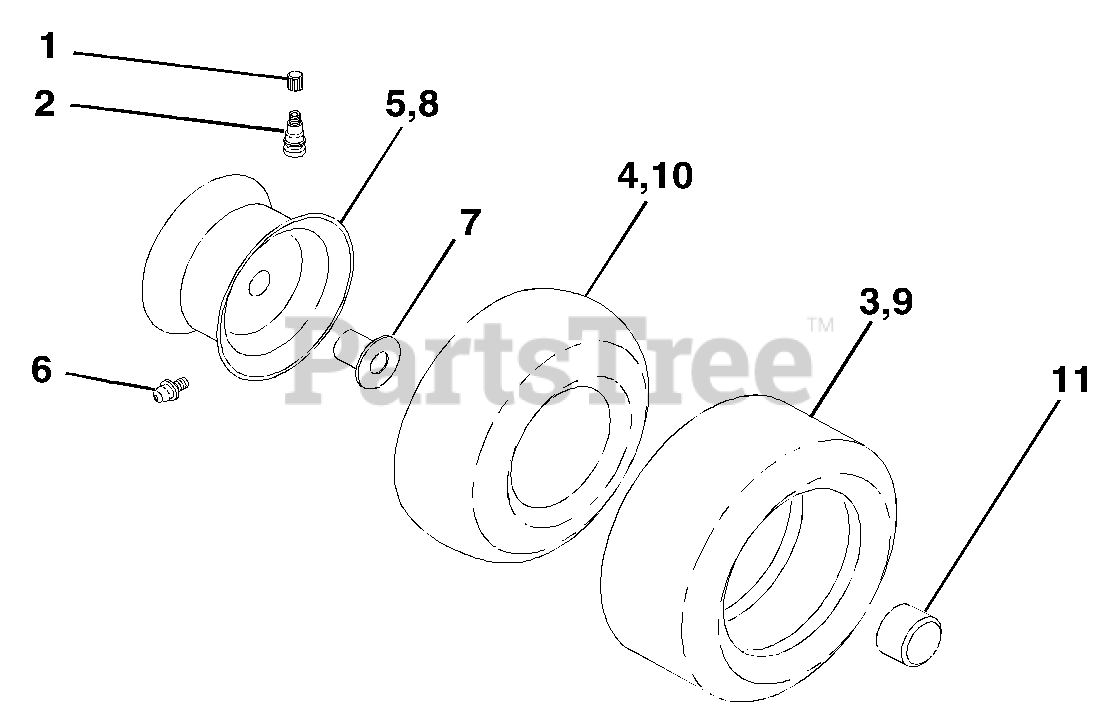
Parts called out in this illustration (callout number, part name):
1	Cap Valve Tire
2	Stem Valve
3	Tire F Ts 15 X 6 0 - 6 Service
4	Tube Front
5	Rim Asm 6" front Silver Service
6	Fitting Grease
7	Bearing Flange
8	Rim Asm 8" rear Silver Service
9	Tire R Ts 18x9 5-8 C Service
10	Tube Rear
11	Cap Axle Blk 1 50 X 1 00
11	Sealant, Tire (10 oz. Tube)
